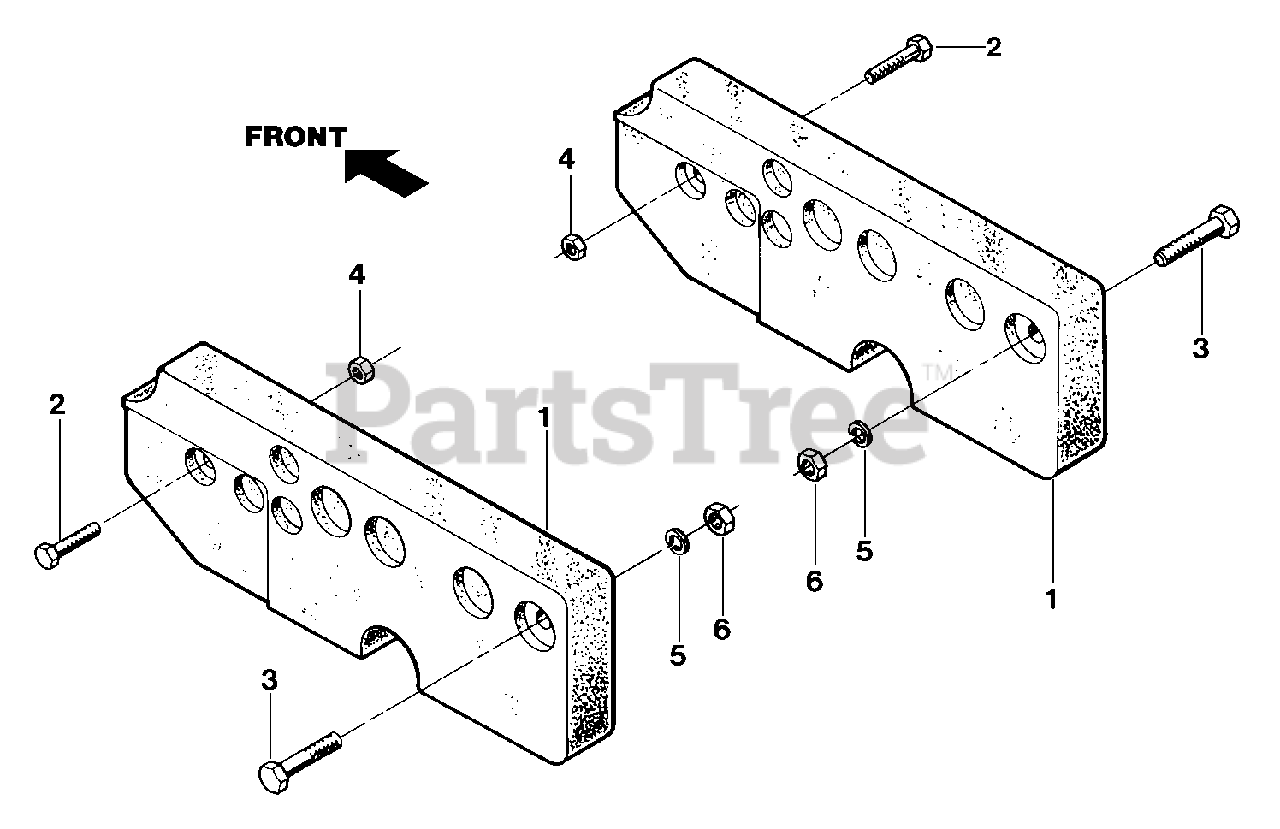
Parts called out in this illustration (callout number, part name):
1	Frame Weight
2	Hex Screw, 1/4-20 x 1-1/4
3	Hex Screw, 5/16-18 x 1-1/2
4	Hex Nut, 1/4-20
5	Lockwasher, 5/16
6	Hex Nut, 5/16-18
